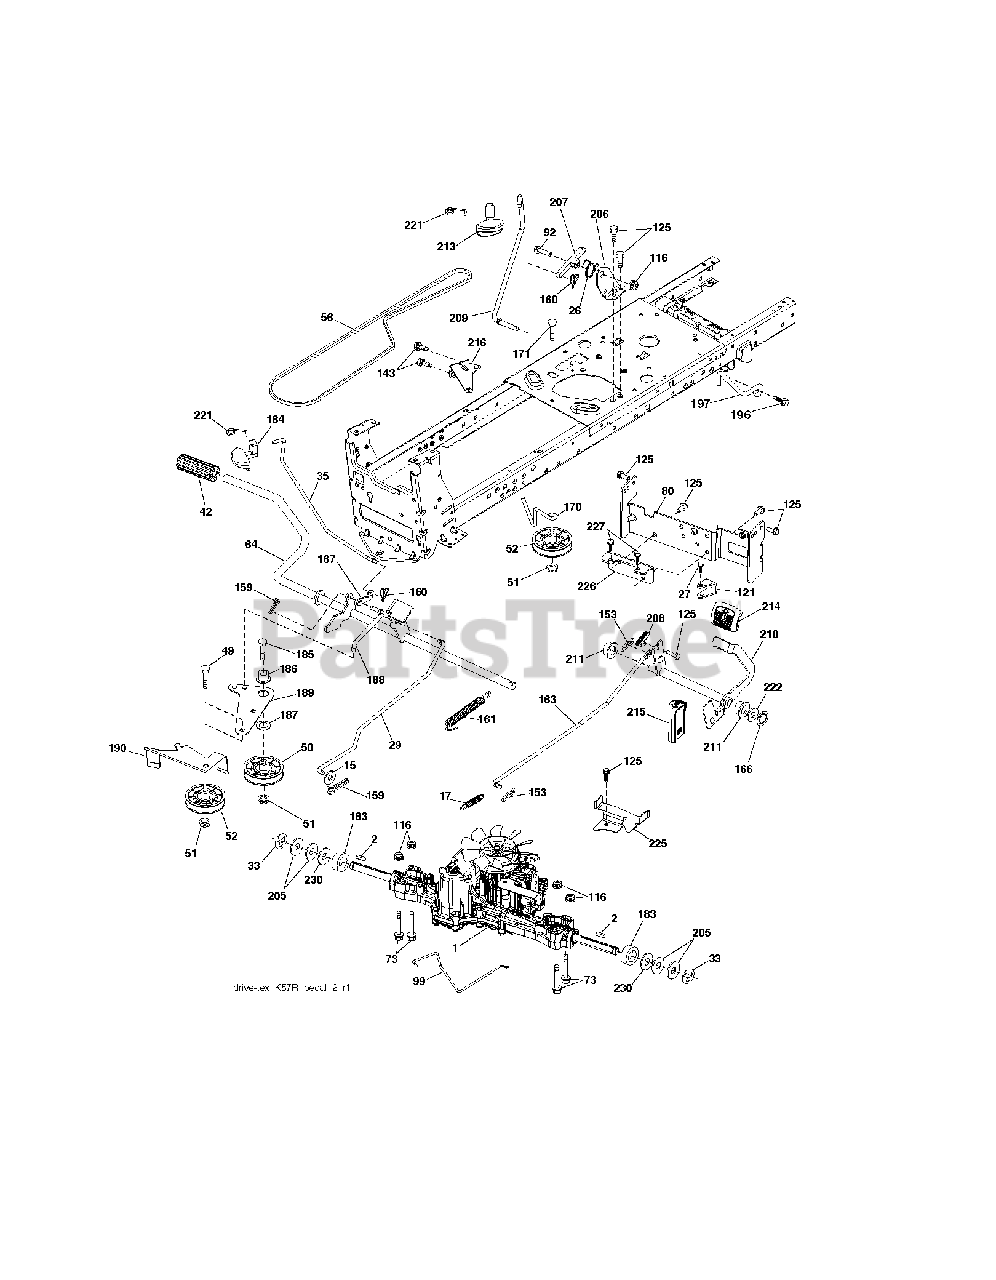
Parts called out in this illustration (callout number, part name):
2	SQUARE KEY
15	WASHER
17	SPRING.BRAKE.K46.GREEN
26	SPRING.RETURN.CRUISE
29	ROD.BRAKE.K46
35	ROD .BRAKE. PARKING. GT. HUSQ.
42	PEDAL COVER T
50	IDLER.FLAT.910.OFFSET
51	NUT LOCK FLG 3/8-16 UNC
52	IDLER.V-GROOVE.910.OFFSET
56	V-BELT.MOWER.92.40.42/K46
64	SHAFT.ASM.PEDAL.BRK.CNTR
80	STRAP.TORQUE.K46.K57R.TT
92	BOLT
99	ROD.SPRING.BYPASS.K46.LT.Z
116	NUT LOCK HEX FLANGE 5/16-18
121	BRACKET.TORQUE.K57R.3POINT
125	SCREW
143	SCREW LT
153	RETAINER M
159	COTTER PIN
160	RETAINER CLIP
161	SPRING, RETURN LT
163	ROD.CONTROL.K57R.K46
166	NUT.PUSH.625
167	LATCH.BRAKE.SPRING
170	KEEPER.V-IDLER.CENTER.
183	SPACER AXLE
184	RB HANDLE.PARKG.BRK.HUS/PRED
186	SPACER.RETAINER
187	WASHER 12/32X2X10GA
188	RP LINK.CLUTCH.GROUND.DRIVE
189	BELLCRANK.GROUND.DRIVE.TEX.
190	KEEPER.BELLCRANK.DRIVE
196	SCREW 3/8-16X1
197	LINK.CLUTCH.ANIT-ROTAT
206	BRACKET.MOUNT.CRUISE.LATCH
207	LATCH.CONTROL.CRUISE
208	GEAR.SECTOR.CONTROL.CR
209	ROD.CONTROL.CRUISE.GT.
210	ROCKER.ASM.PEDAL.CONTR
211	BEARING.NYLON
213	KNOB.CONTROL.CRUSIE.HU
214	PEDAL.FORWARD.PAD.TEX
215	PEDAL.REVERSE.TEX.GT.4
216	BRACKET.PULLEY.IDLER.W/TEX
221	RETAINER.SPRING.CLIP.H
222	WASHER 21/32 X 1-1/4 X 10 GA.
225	KEEPER.BELT.TRANSAXLE.K46
226	BRACKET.MOUNT.TORQUE.K46.TLT
227	SCREW
230	WASHER.HARDENED
